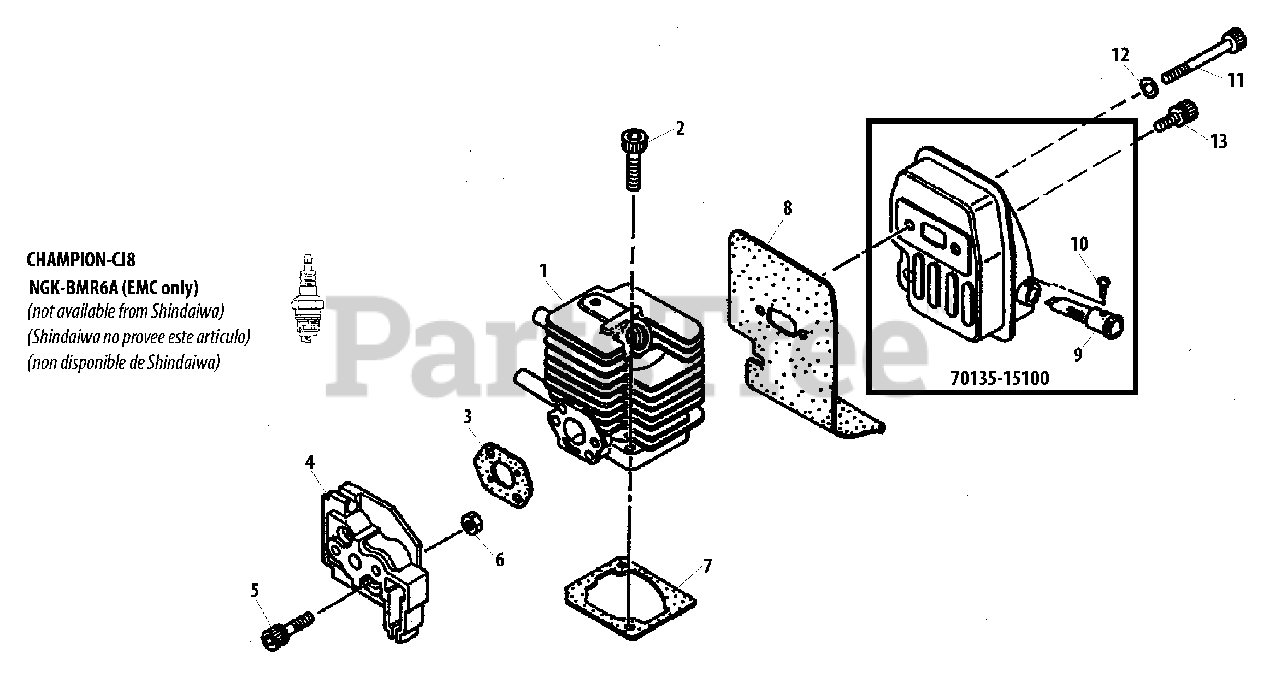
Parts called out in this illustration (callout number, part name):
1	CYLINDER
2	SCREW - 5X25
3	GASKET
4	INSULATOR
5	SCREW - 5X30
6	NUT
7	GASKET, CYLINDER
8	SHIELD, EXHAUST
9	SCREEN, SPARK ARRESTOR
10	SCREW - 3X6
11	SCREW - 5X50
12	WASHER - 5
13	SCREW - 5X12
70135-15100	MUFFLER ASSY
